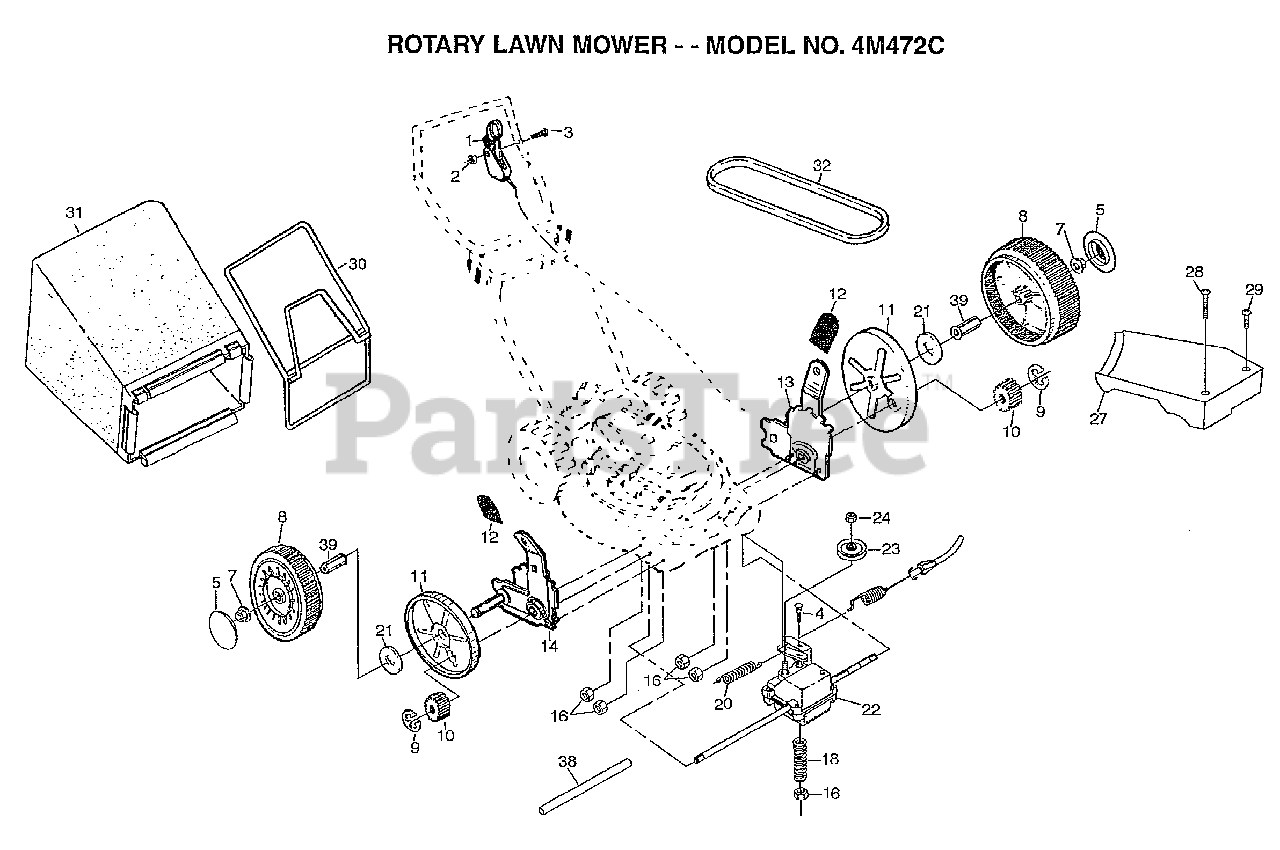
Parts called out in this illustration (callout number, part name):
1	CONTROL.DRV.56.25
3	SCREW.HXHD.WASH.
4	BOLT.1/4-20X2.0
5	HUB CAP
7	NUT.HXFLG.LOCK.
8	WHEEL.8X2.LP.PR
9	E-RING.7/16.RE.
10	PINION.GEAR
11	DUST SHROUD PM
12	KNOB PM
13	SELECTOR ASSY LH
14	SELECTOR ASSY RH
18	SPRING.TENSION
20	SPRING
21	WASHER FLUT
23	PULLEY.DRIVEN
24	LOCKNUT
27	"COVER.DRIVE 22""RD"
28	SCREWL.SLOT.TORXT
29	SCREW.SLOT.TORTX.
30	FRAME.CATCHER.2.5
31	GRASSBAG.250B1.BL
38	DRV SHAFT TUBE PM
39	BUSHING.HEX
